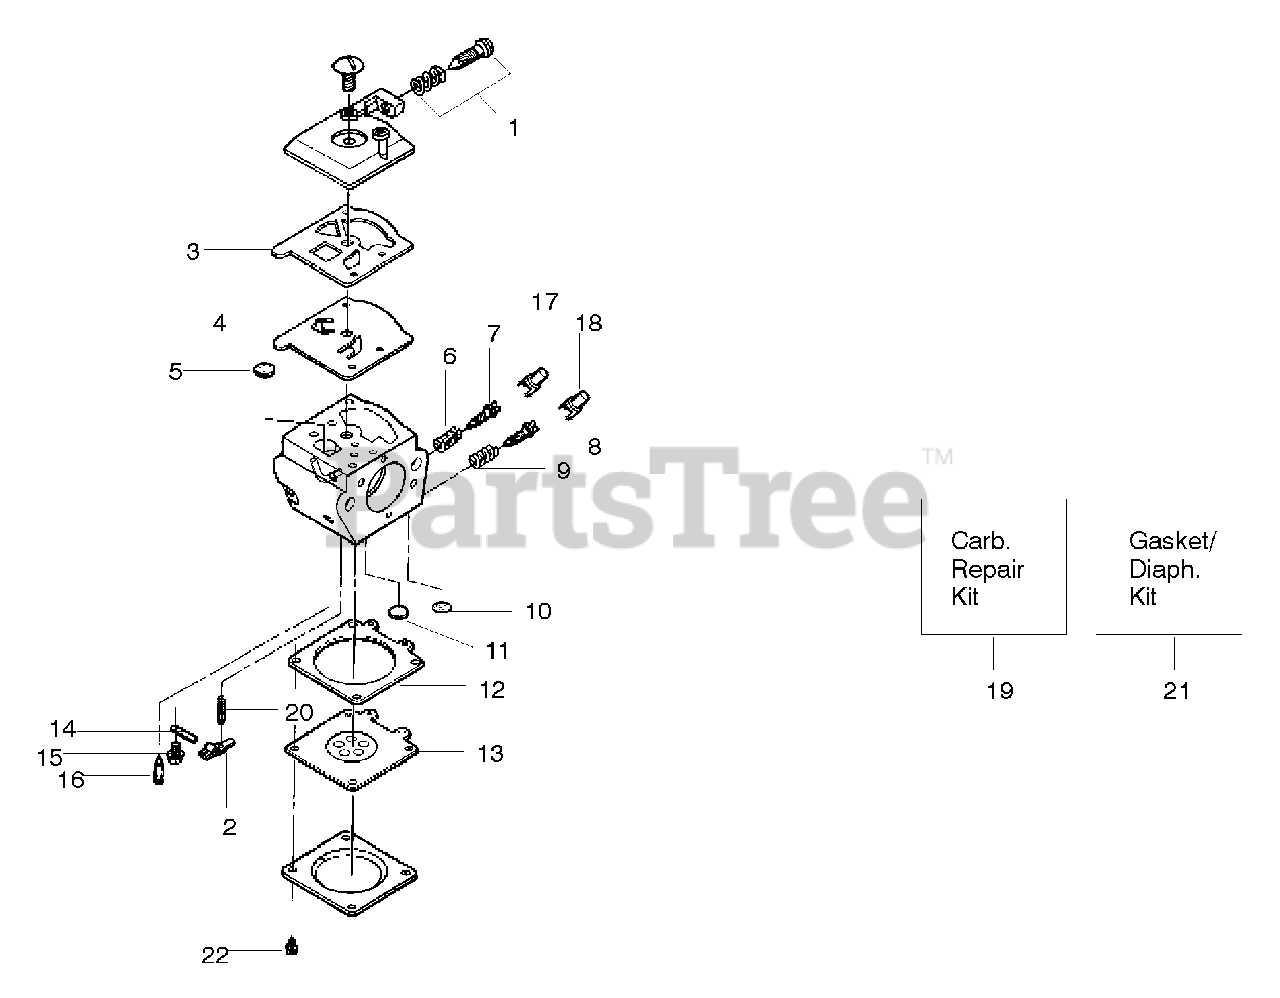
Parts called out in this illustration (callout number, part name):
1	Idle Adv. Screw Kit
2	Metering Lever
3	Fuel Pump Gasket
4	Fuel Pump Diaphragm
5	Fuel Inlet Screen
6	Needle Spring (Low Speed)
7	Low Speed Needle
8	High Speed Needle
9	Needle Spring (High Speed)
10	Welch Plug (5/16)
12	Metering Diaphragm Gasket
13	Metering Diaphragm
14	Metering Lever Pin
15	Metering Lever Pin Screw
16	Inlet Needle Valve
17	Limiter Cap High
18	Limiter Cap Low
19	Carburetor Repair Kit Walbro
19	Carburetor Repair Kit Zama
20	Metering Lever Spring
21	Gasket/Diaphragm Kit Walbro
21	Gasket/Diaphragm Kit Zama
22	Metering Cover Screw Ass'y
